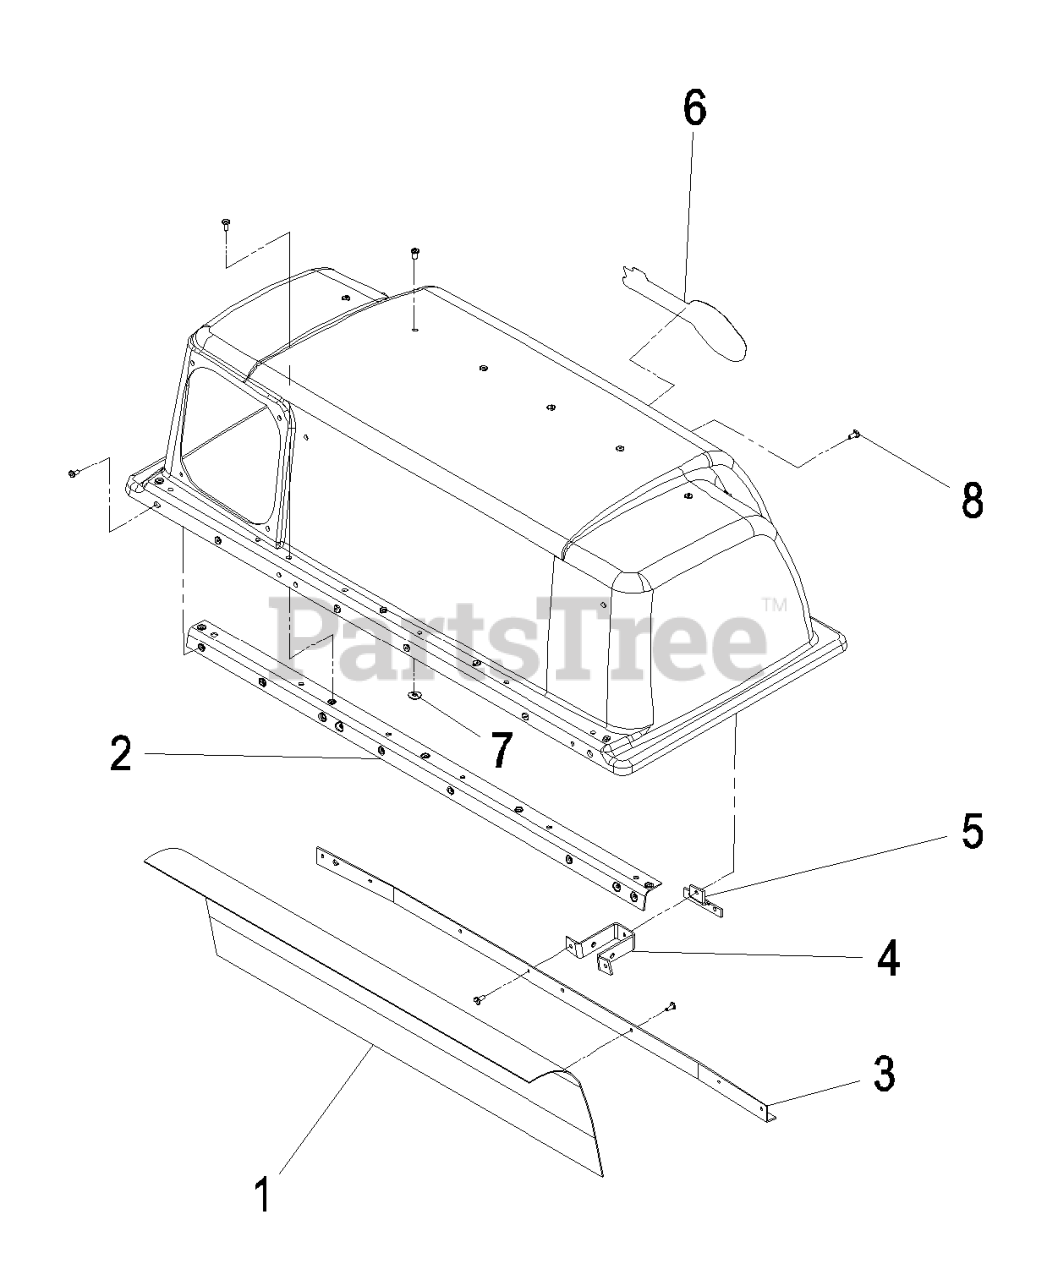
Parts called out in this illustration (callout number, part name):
1	SCREEN-BAGGER
2	STIFFENER-BAGGER, TOP
3	SUPPORT-SCREEN
4	ANCHOR-LATCH
5	REINFORCEMENT-LATCH
6	DECAL, EXMARK LOGO
7	WASHER-FLAT
8	RIVET-BLIND
